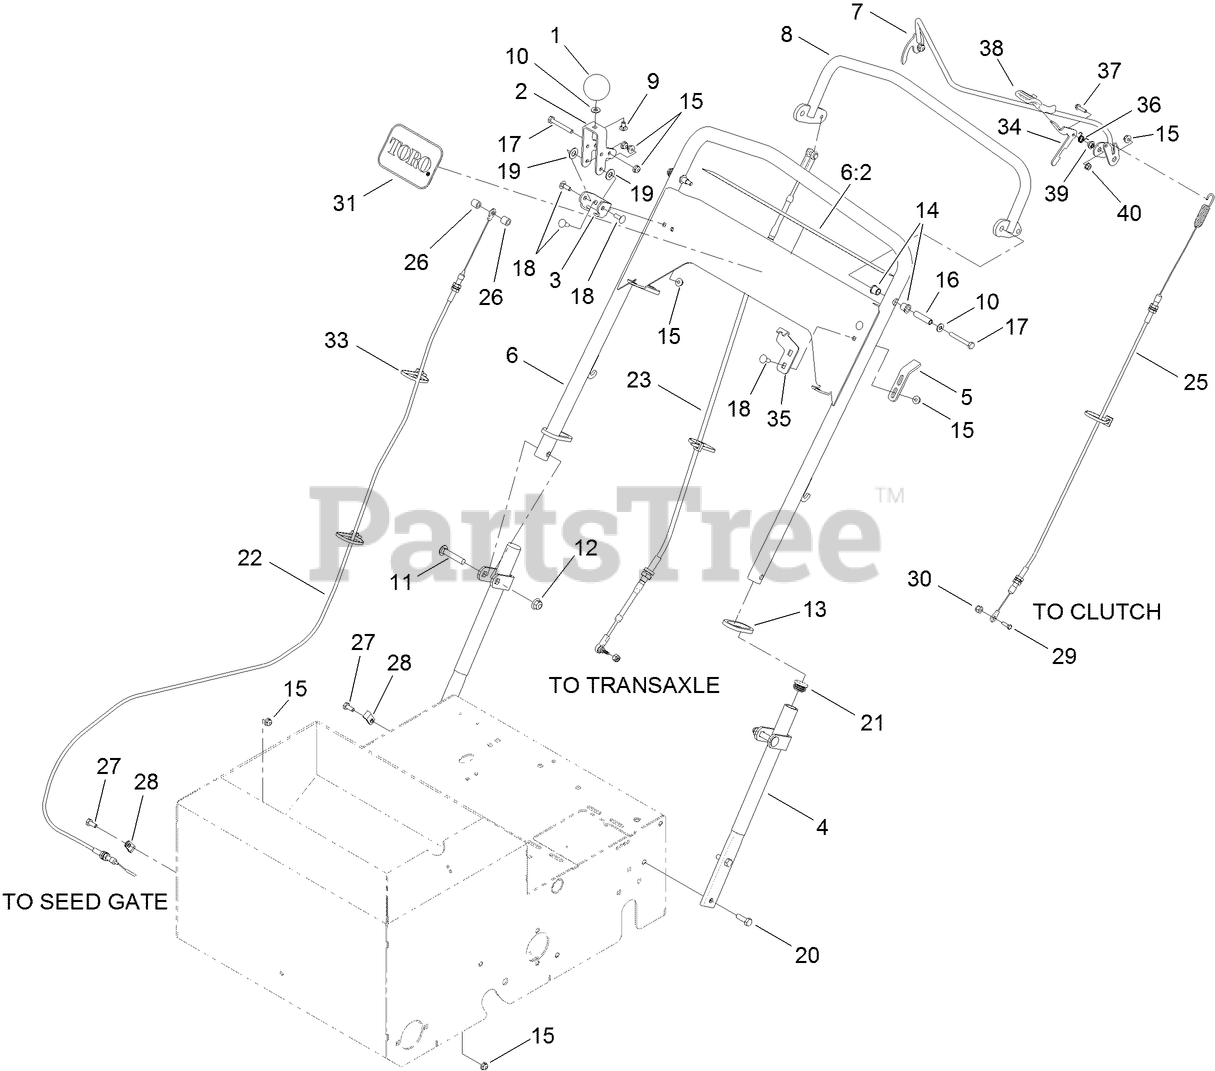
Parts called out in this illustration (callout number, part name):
1	KNOB-RATE, FLOW
2	LEVER-ADJUST, FLOW
3	BRACKET-ADJUST, FLOW
4	HANDLE-LOWER
5	BRACKET-ADJUST, DRIVE
6	HANDLE ASM
6:2	DECAL-CONTROL PANEL
8	HANDLE-DRIVE
9	SCREW-CARR
10	WASHER-FLAT
11	SCREW-CARR
12	NUT-HF, NI
13	RING-HANDLE LOCK
14	BEARING
15	NUT-HF
16	BUSHING-PIVOT
17	SCREW-HH
18	BOLT-CARR
19	WASHER-PLAIN
20	SCREW-HH
22	CABLE-SEED FLOW
23	CABLE-PUSH PULL
25	CABLE-CLUTCH
26	SPACER
27	SCREW-HH
28	CLAMP-R
30	NUT-LOCK
33	TIE-CABLE
35	BRACKET-2 STEP, CATCH
36	SPRING-TORSION
37	SCREW-HWH
39	SPACER
40	NUT-LOCK, FLANGE
